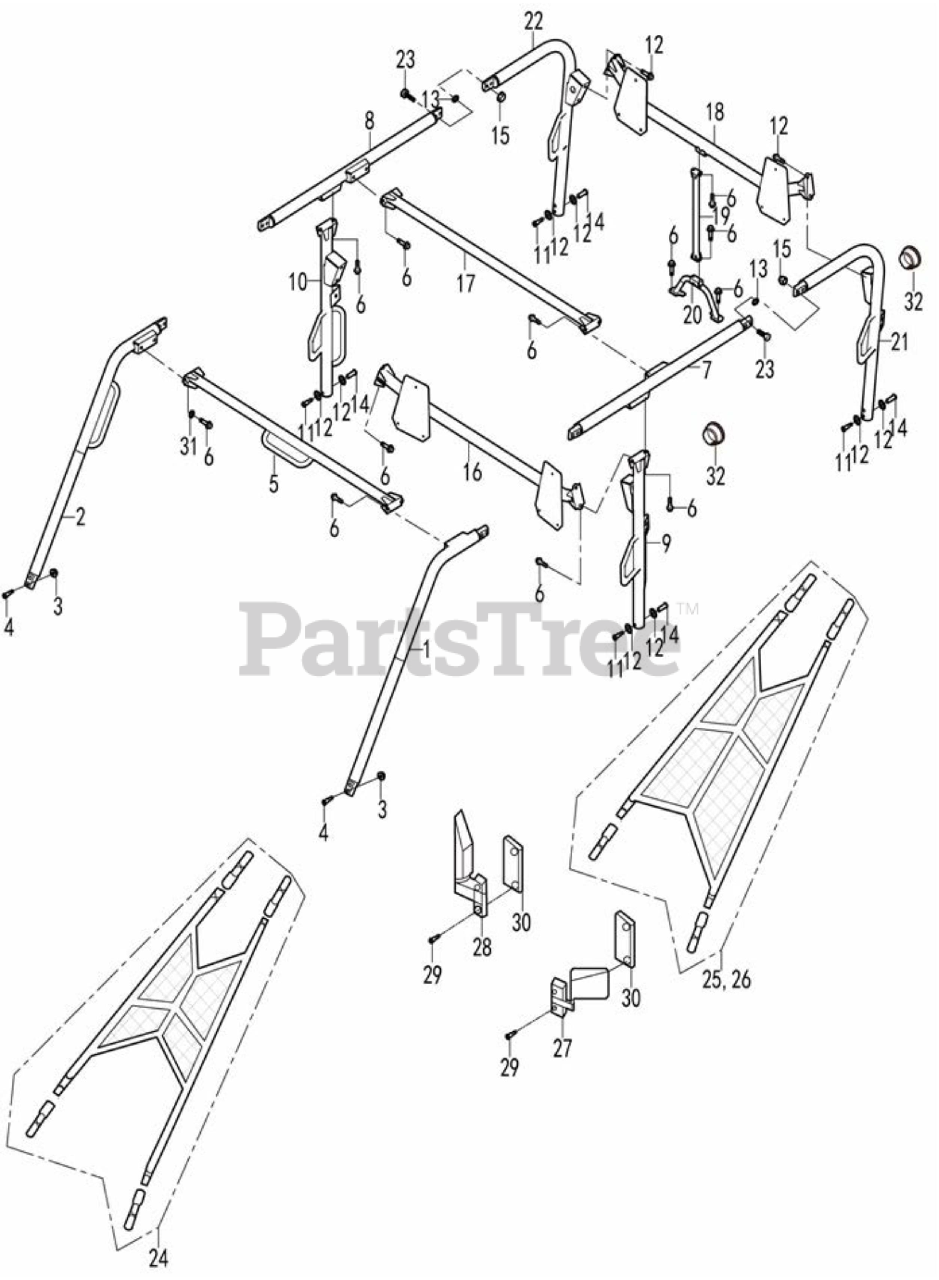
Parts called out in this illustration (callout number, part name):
1	Roof Rod Assy I
2	Roof Rod Assy II
3	Hexagon Flange Self-Lock Nuts M10x1.25
4	Hexagon Flange Bolt M10X1.25X50
5	Roof Rod Assy III
6	Hexagon Flange bolt M10X1.25X20
7	Roof Rod Assy IV
8	Roof Rod Assy V
9	Roof Rod Assy VI
10	Roof Rod Assy VII
11	Step bolt M8X22-10X16
12	Curved Washer
13	Spring Washer10
14	threaded sleeve,sphere
15	Nut M10X1.25
16	Roof Rod Assy VIII
17	Roof Rod Assy IX
18	Roof Rod Assy ?
19	Roof Rod Assy ?
20	Roof Rod Assy VII
21	Roof Rod Assy X
22	Roof Rod Assy XI
23	Socket Hexagon Head Screw M10X1.25X25
24	protecting wire net I
25	protecting wire net I
26	protecting wire net II
27	Left Rear Mirror
28	Right Rear Mirror
29	Socket Hexagon Head Screw M6X30
30	Mounting Seat,rearview mirror
31	Flat Washer 10
32	Rubber plug 29X37
